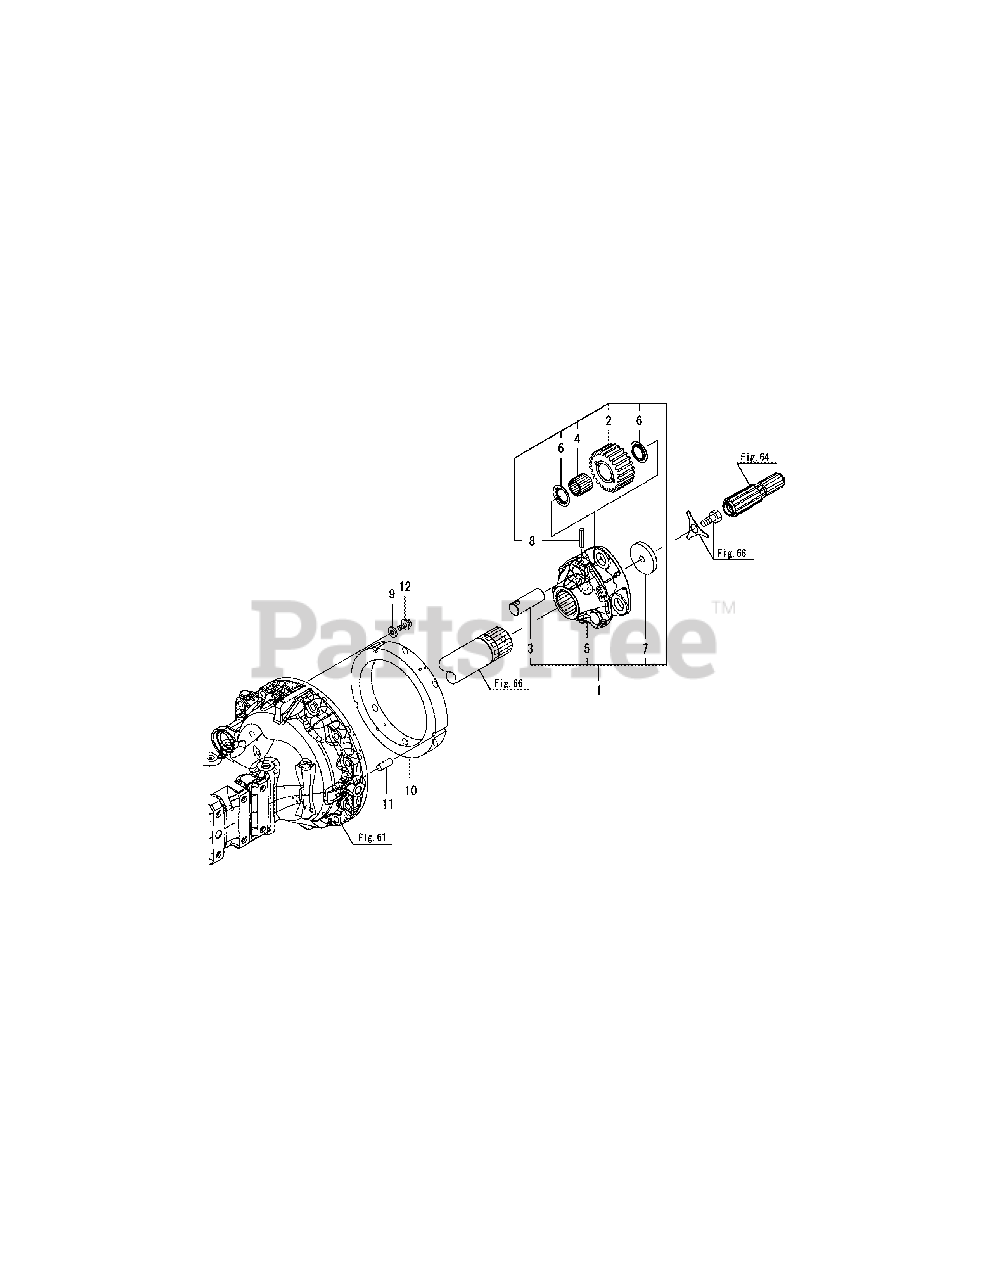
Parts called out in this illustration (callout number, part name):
1	CARRIER ASSY, PLANET
2	PINION, PLANETARY
3	SHAFT, PLANETARY
5	CARRIER, PLANETARY
6	WASHER, 26X44X4
7	WASHER 13X64X9
8	SPRING PIN 8X40
10	GEAR, INTERNAL
11	PARALLEL PIN, M12X32
12	BOLT M 8X 16 PLATED
